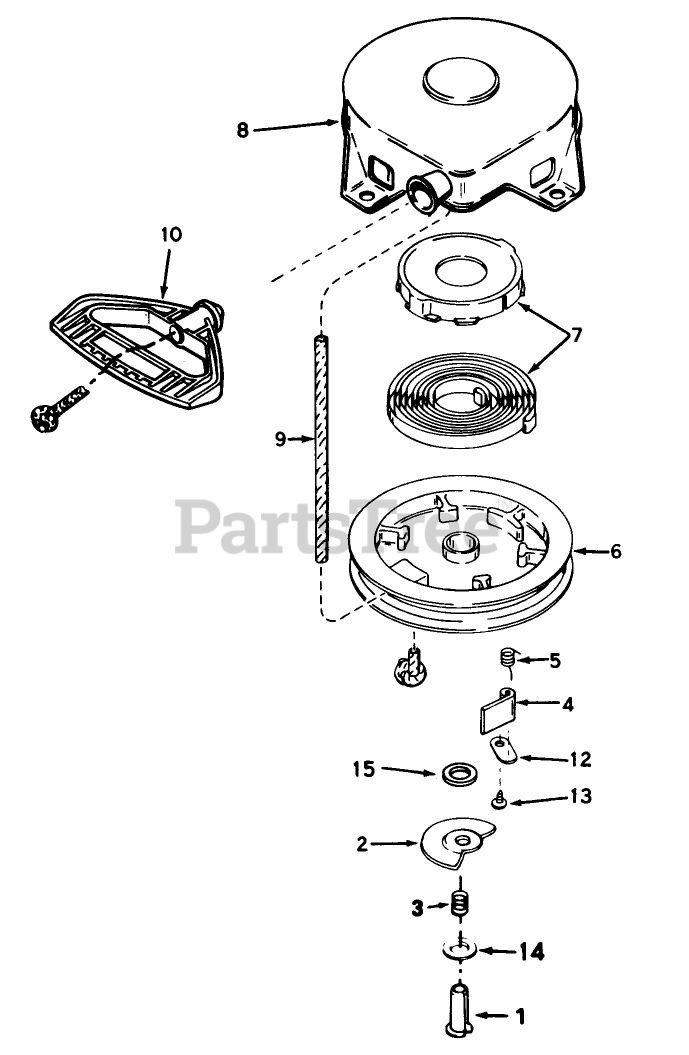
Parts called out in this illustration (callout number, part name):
1	Pin, Spring (Incl. Ref. #7)
2	Washer
3	Brake Spring
4	Dog-Starter
5	Spring-Dog
6	Pulley
7	Spring Keeper Assy
8	Housing-Starter
9	Rope-Starter
10	Handle-Starter, Mitten Grip
12	Retainer-Dog
13	Screw
14	Washer
15	Washer
